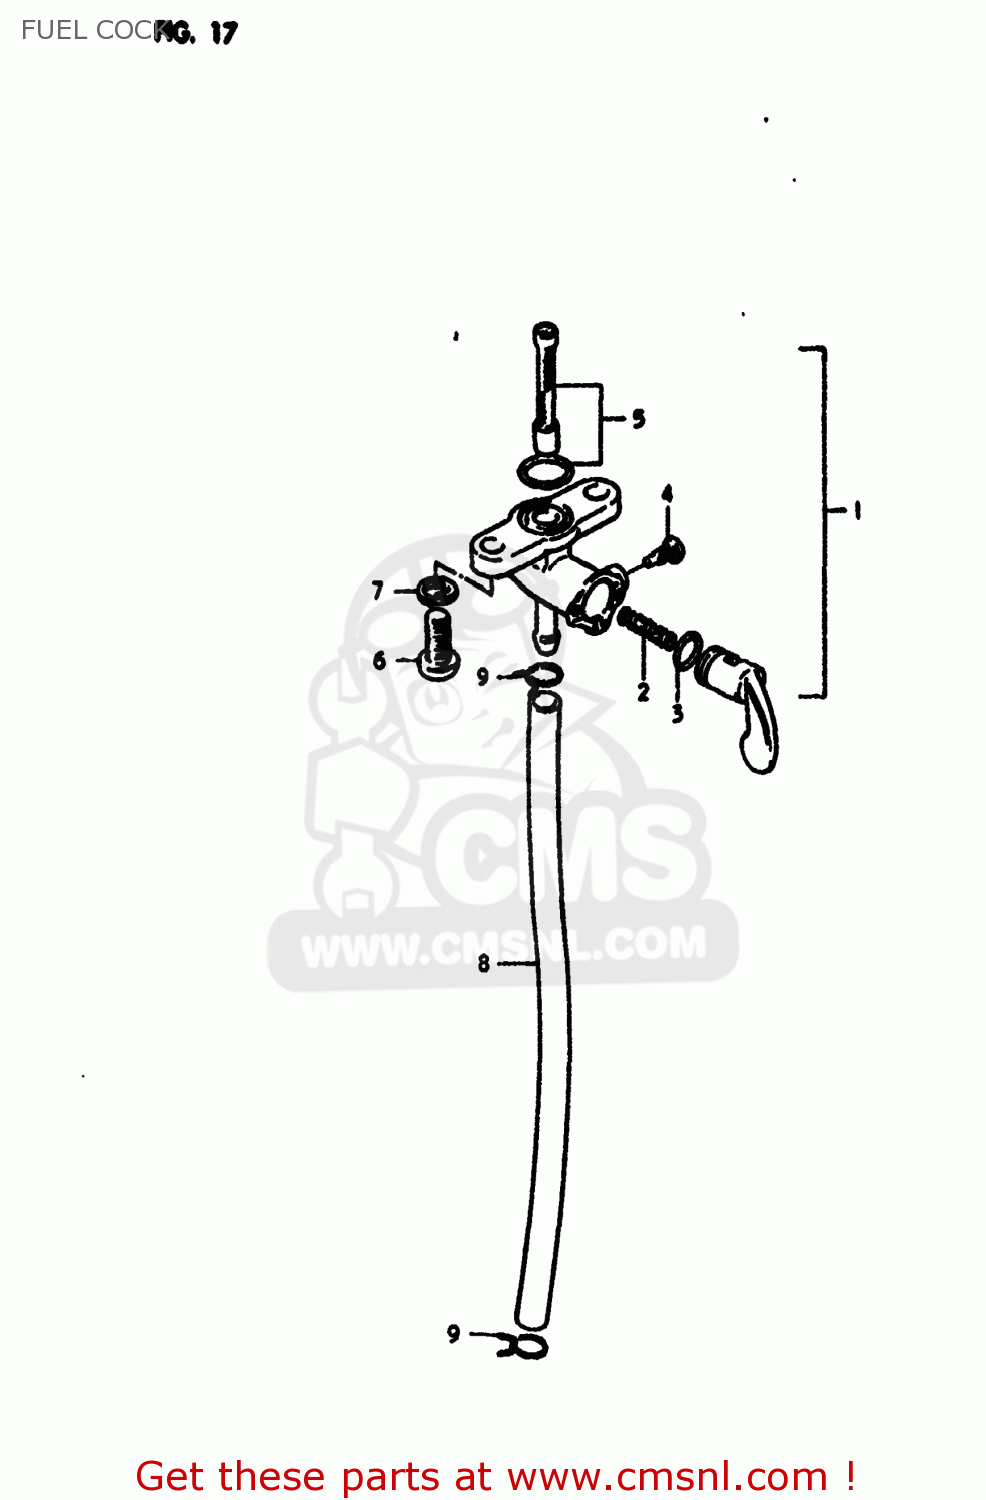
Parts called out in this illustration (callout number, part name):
1	COCK ASSEMBLY,FUEL
2	SPRING,FUEL COCK VALUE
3	O RING,LEVER
4	SCREW
5	FILTER SET FUEL
6	SCREW
7	LOCK WASHER
8	HOSE
9	CLAMP
